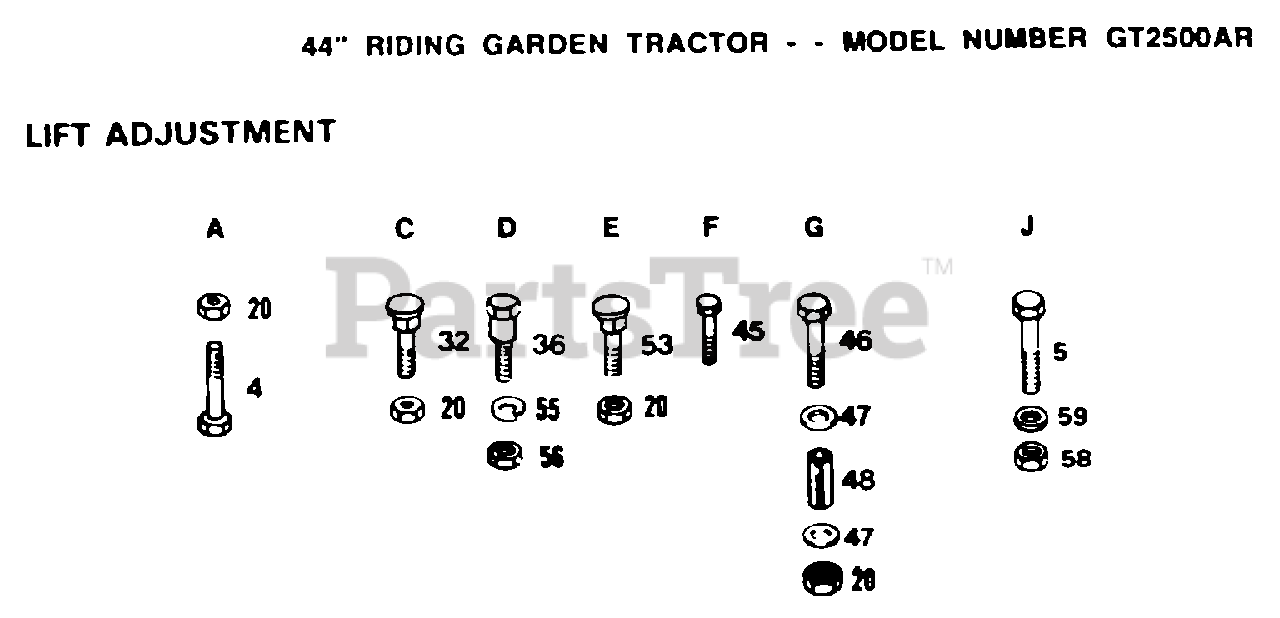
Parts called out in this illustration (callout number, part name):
5	ROD ASSEM YT
32	BOLT
36	"BOLT, SHOULDER LT"
45	SCREW
47	WASHER GT
55	WASHER T
56	NUT SPECIAL T
59	WASHER
